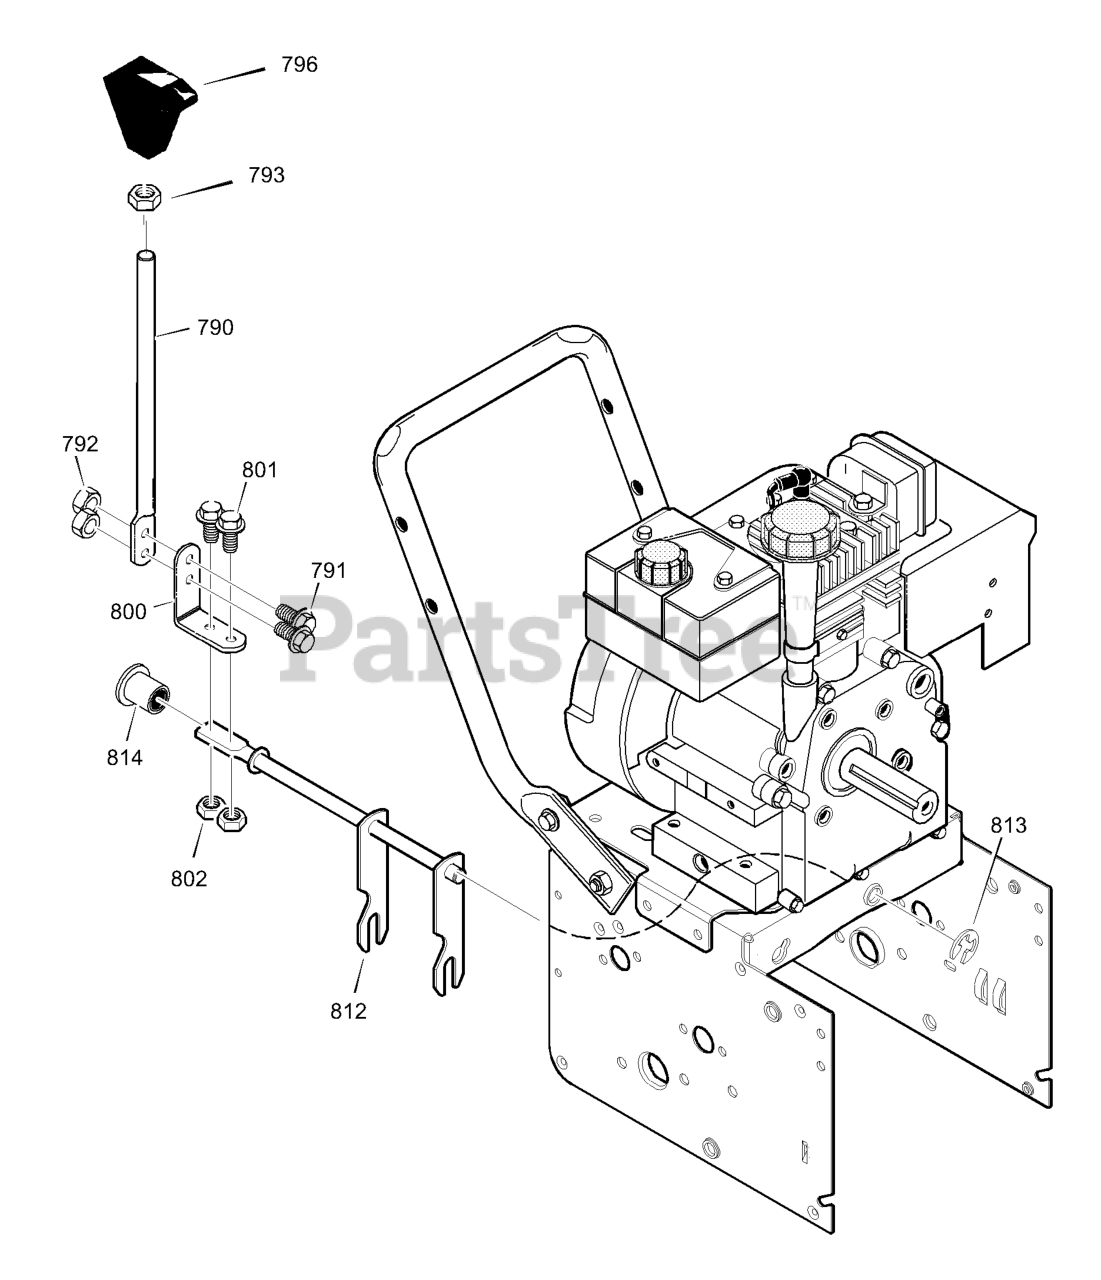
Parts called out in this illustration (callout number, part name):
790	ROD, SHIFT
791	SCREW, 1/4-20X.75
792	NUT, 1/4-20
793	NUT, JAM
796	KNOB, SLIP
800	LEVER, SPRING
801	SCREW, 1/4-20X.75
802	NUT, 1/4-20
811	BEARING, FLANGED
812	ROD ASSY., SPEED SELECT
813	RETAINER, RING
